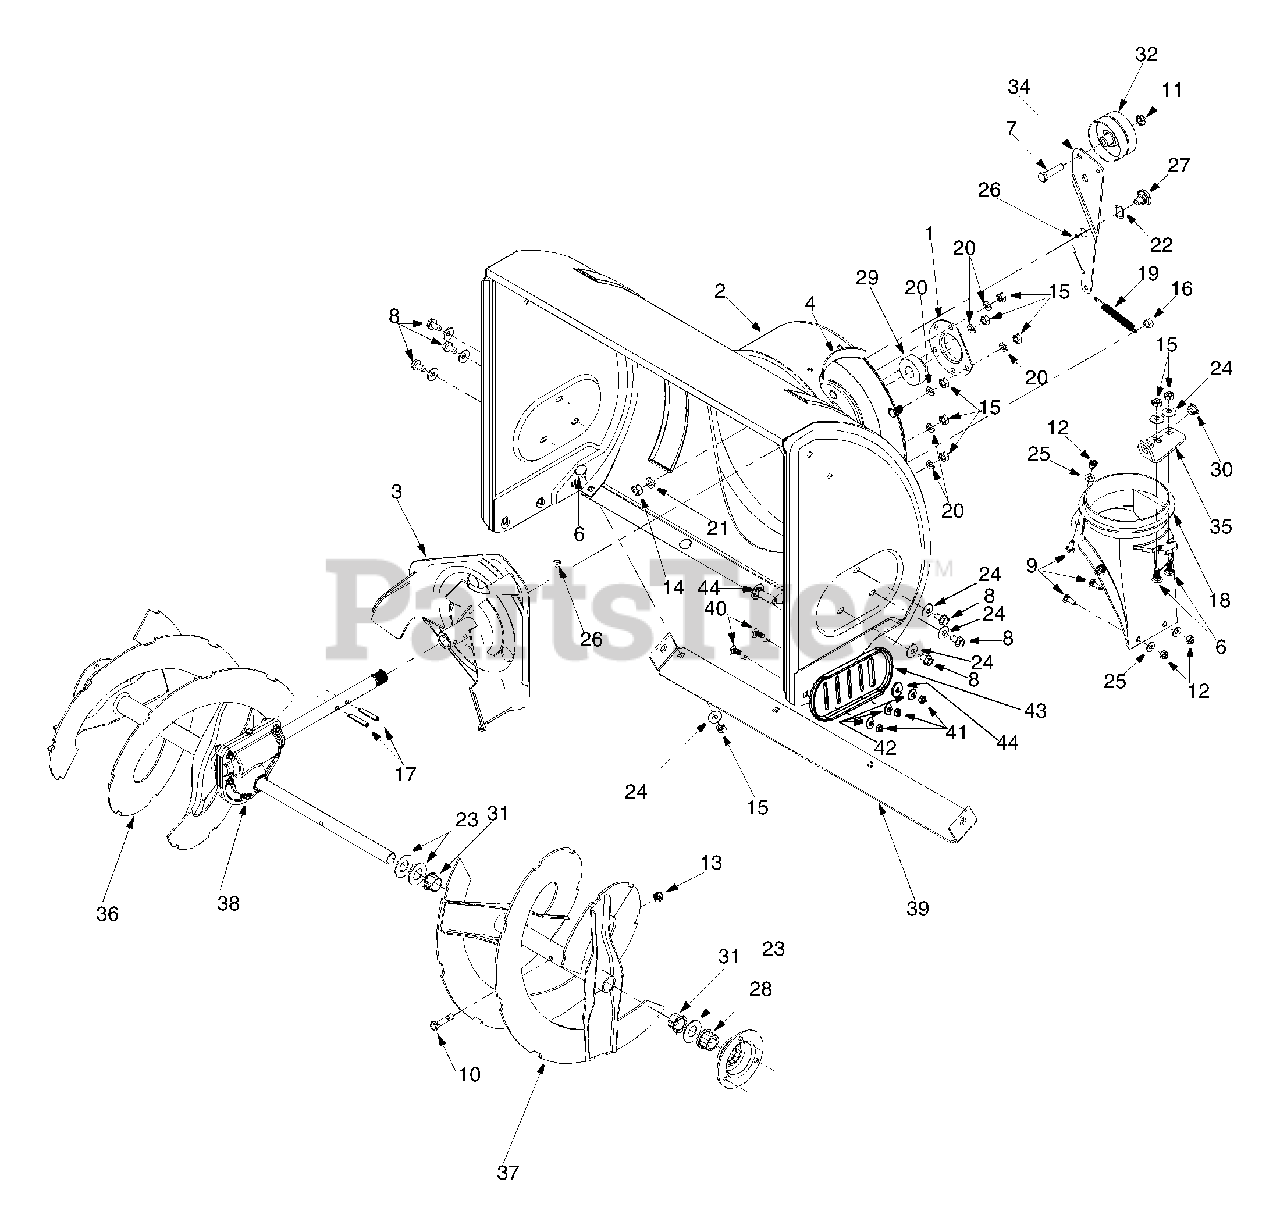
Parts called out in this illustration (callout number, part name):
1	Bearing Housing
2	Auger Housing Assy. 28" Polo Green
4	Chute Reinforcement: Polo Green
6	Carriage Bolt 5/16-18 x .75" Gr.2
7	Hex Screw 3/8-24 x 1.5" Gr.5
8	Hex Washer Head Self-Tapping Screw 5/16-18 x .62"
9	Carriage Screw 1/4-20 x .75"
10	Shear Bolt 5/16-18 x 1.5"
11	Jam Nut 3/8-24
12	Hex Lock Nut 1/4-20
13	Hex Lock Nut 5/16-18
14	Hex Nut 3/8-16 Gr.2
15	Hex Nut 5/16-18 Gr.5
16	Hex Patch Nut 5/16-18
17	Spiral Pin
18	Chute Adapter
19	Extension Spring
20	Lock Washer
21	Lock Washer
22	Wave Washer
23	Flat Washer
24	Belleville Washer
25	Flat Washer
26	Grease
27	Shoulder Screw
28	Hex Flange Bearing
29	Flange Ball Bearing
30	Bushing
31	Flange Bushing
32	Flat Idler
36	Spiral Assembly: RH 28" Powder Black
37	Spiral Assembly: LH 28" Powder Black
38	Gear Assembly: Auger 28"
40	Carr. Bolt: 5/16-18 x 0.75"
41	Hex Nut: 5/16-18 Gr.5
42	Belleville Washer
43	Slide Shoe: Polo Green
44	Carriage Screw: 5/16-18 x 1.0"
